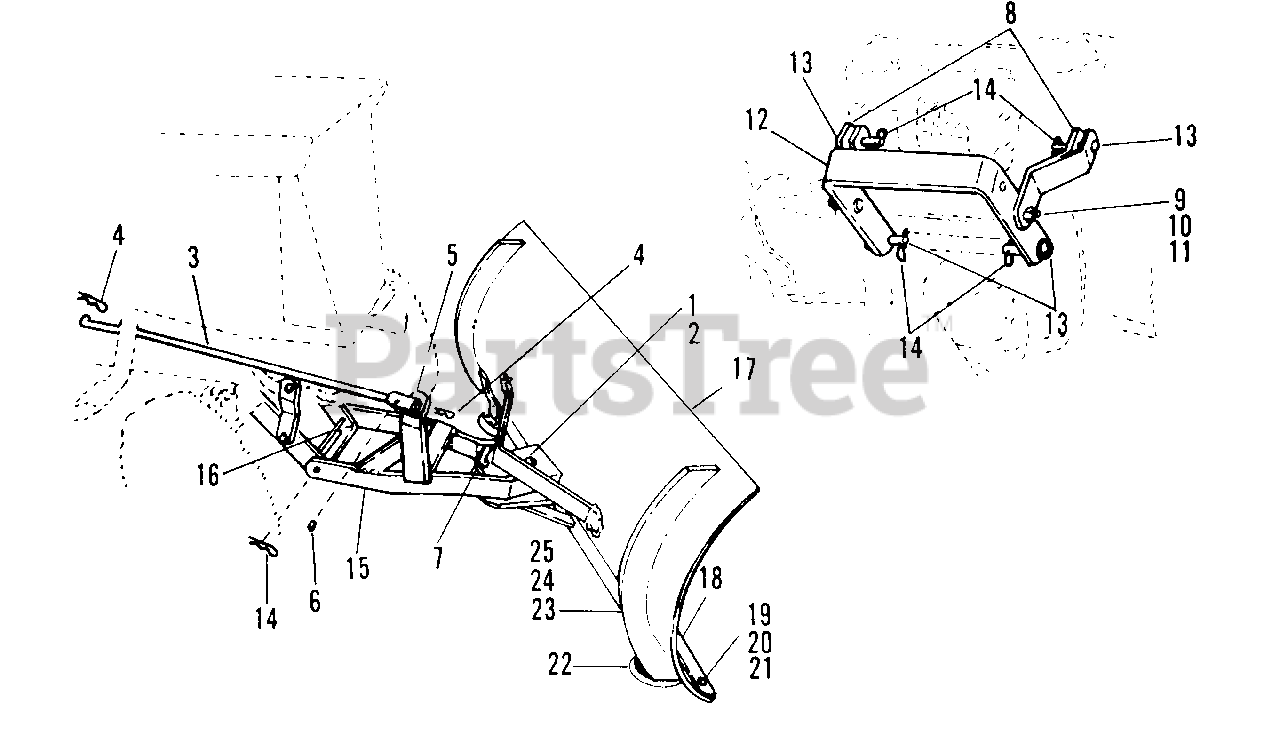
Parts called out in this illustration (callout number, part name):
2	CLIP, Hairpin
3	ROD, Lift
4	CLIP, Hairpin
5	GUIDE ASSY, Lift Rod
6	SETSCREW, 5/16-18 x 3/8
8	ARM ASSY., Support
9	CAPSCREW, Hex, 3/8-16 x 1-1/4
10	LOCKWASHER, 3/8
11	NUT, Hex, 3/8-16
12	FRAME, Push
13	PIN
14	CLIP, Hairpin
15	PUSH BAR ASSY.
16	ROD, Pivot
17	BLADE ASSY., 42"
18	PLATE, Wear
19	BOLT, Carriage, 3/8-16 x 3/4
20	LOCKWASHER, 3/8
21	NUT, Hex, full, 3/8-16
22	SHOE ASSEMBLY
23	BOLT, Carriage, 3/8-16 x 1
24	LOCKWASHER, 3/8
25	NUT. Hex full 3/8-16
